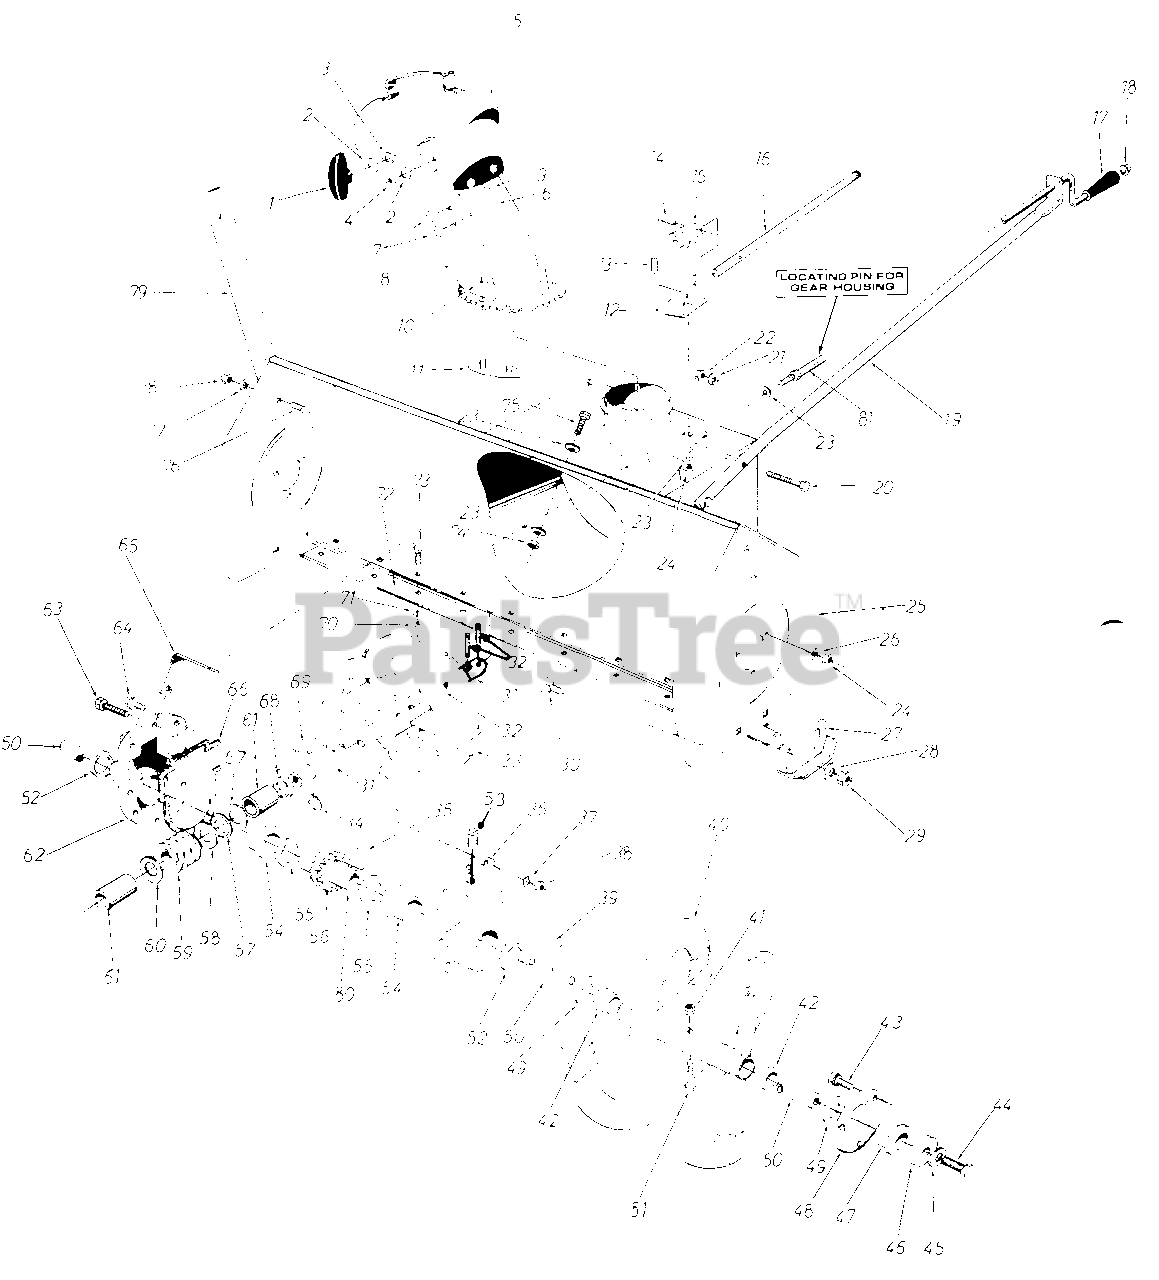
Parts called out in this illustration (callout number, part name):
1	Hand Knob Ass'y.
2	Bell. Wash. .345 I.D. x .88 O.D. x .060
3	Fl.-Wash. .312 I.D. x 1.125 O.D. x .125
4	Hex Cent. L-Nut 5/16-18 Thd.
5	Top Chute Ass'y .
6	Carriage Bolt 5/16-18 x 1.50" Lg.
7	Fl.-Wash. .53 I.D. x 1.25 O.D. x .100
8	Chute Ass'y.
9	Carriage Bolt 5/16-18 x 1.00" Lg.
10	Hex Cent. L-Nut 1/4-20 Thd.
11	Chute Flange Keeper Ass'y.
12	Chute Bracket
13	Carriage Bolt 5/16-18 x .62" Lg.
14	Spring Pin Roll 1/8" Dia. x .75" Lg.
15	Worm-R.H. w hree Threads
16	Chute Crank
17	Knob Black 3/8" Dia. Hole
18	Push Nut 3/8" rod.
19	Chute Crank Support Tubing
20	Hex Scr. 3/8-24 x 1.25" Lg.*
21	L.-Wash. 3/8" Scr.*
22	Hex Ins.Jam L.-Nut 3/8-24 Thd.
23	Bell.-Wash. .345 I.D. x .88 O.D. x .060
24	Hex Nut 5/16-18 Thd.
25	Blower Housing Assembly
26	L-Wash. 5/16" Scr.*
27	Slide Shoe
28	Bell. Wash. .400 I.D. x .88 O.D. x .060
29	Hex Nut 3/8-16 Thd.
30	Carriage Bolt 3/8-16 x .75" Lg.
31	Blower Axle
32	Spring Pin Spiral 5/16" Dia. x 1.75" Lg.
33	Blower Fan Ass'y.
34	Snap Ring for .875" Dia. shaft
35	91 Woodruff Key 1/4" x 3/4" Dia.
36	Gear Housing Half- L.H.
37	L.-Wash. 5/16"Scr.*
38	Hex Ins. L.-Nut 5/16-18 Thd.
39	#91 Woodruff Key 1/4" x 3/4" Dia.
41	Hex Ins. L-Nut5/16-18 Thd.
42	Plastic Bushing
43	Hex Sems Scr. 5/16-18 x .75" Lg.
44	Hex Scr. 5/16-18 x .88" Lg. Speco
45	BellevilleWash. .345" I.D. x .88" O.D.
46	Wash. .390 I.D. x 1.75" O.D. x 3/16" Thk.
47	Flange Bearing w/flats 1.00" I.D.
48	Bearing Housing
49	Fl-Wash. 1.00" I.D. x 1.75' O.D. x .100
50	Spiral Axle
51	Hex Scr. 5/16-18 x 1.75" Lg.*
52	Oil Seal-1.50" I.D.
53	Sq. Hd. Pipe Plug 3/8" Thd.
54	Flange Bearing 1.503 I.D.
55	Fl.-Wash. 1.50" I.D. x 2.0" O.D. x .030
56	Double Threaded Worm Gear-L.H.
57	Thrust Bearing .88" I.D. x 1.44" O.D.
58	Fl.-Wash. .88" I.D. x 1.5" O.D. x .030
59	Double Threaded Worm-L.H.
60	Fl-Wash. .88 I.D. x 1.4" O.D. x .155
61	Sleeve
62	Gear Housing Half-R.H.
63	Hex Scr. 5/16-18 x 1.25" Lg.*
64	Hex Scr. 5/16-18 x 1.00" Lg.*
65	Gear Housing Support Brkt
66	Rubber Gasket
67	Fl.-Wash. .88" I.D. x 1.4" O.D. x .155
68	Oil Seal. .875" I.D.
69	#9 Hi-Pro Key 3/16" x 3/4" Dia.
70	Hex Nut 5/16-18 Thd.*
71	L.-Wash. 5/16" Scr.*
73	Carriage Bolt 5/16-18 x .75" Lg.*
74	Hex Nut 5/16-18 Thd.*
75	Hex Scr. 5/16-18 x .75" Lg.*
76	Carriage Bolt 5/16-18 x .62" Lg.*
77	L.-Wash. 5/16" Scr.*
78	Hex Nut 5/16-18 Thd.*
79	Guide Blade
80	Worm Gear Shaft
81	Stud 3/8-16 x 2.75" Lg.
